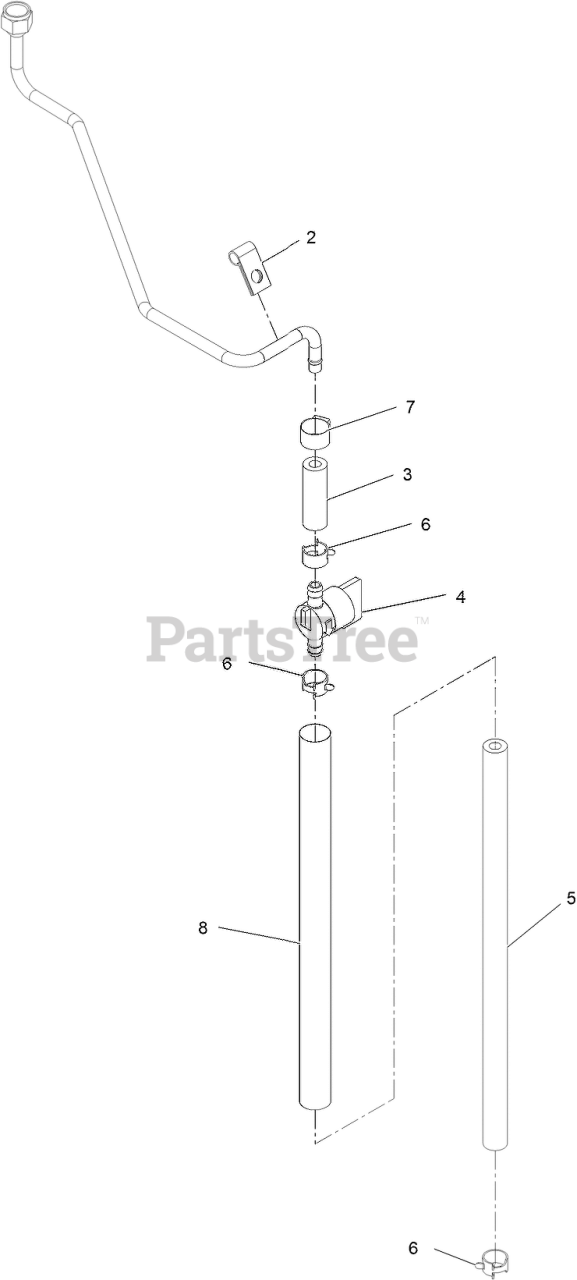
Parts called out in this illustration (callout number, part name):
2	CLIP-CLOSED, INSULATED
3	Hose-Fuel
4	VALVE-FUEL
5	HOSE-FUEL
6	CLAMP-HOSE
7	Clamp-Hose, Fuel
8	Sleeve, Thermal
